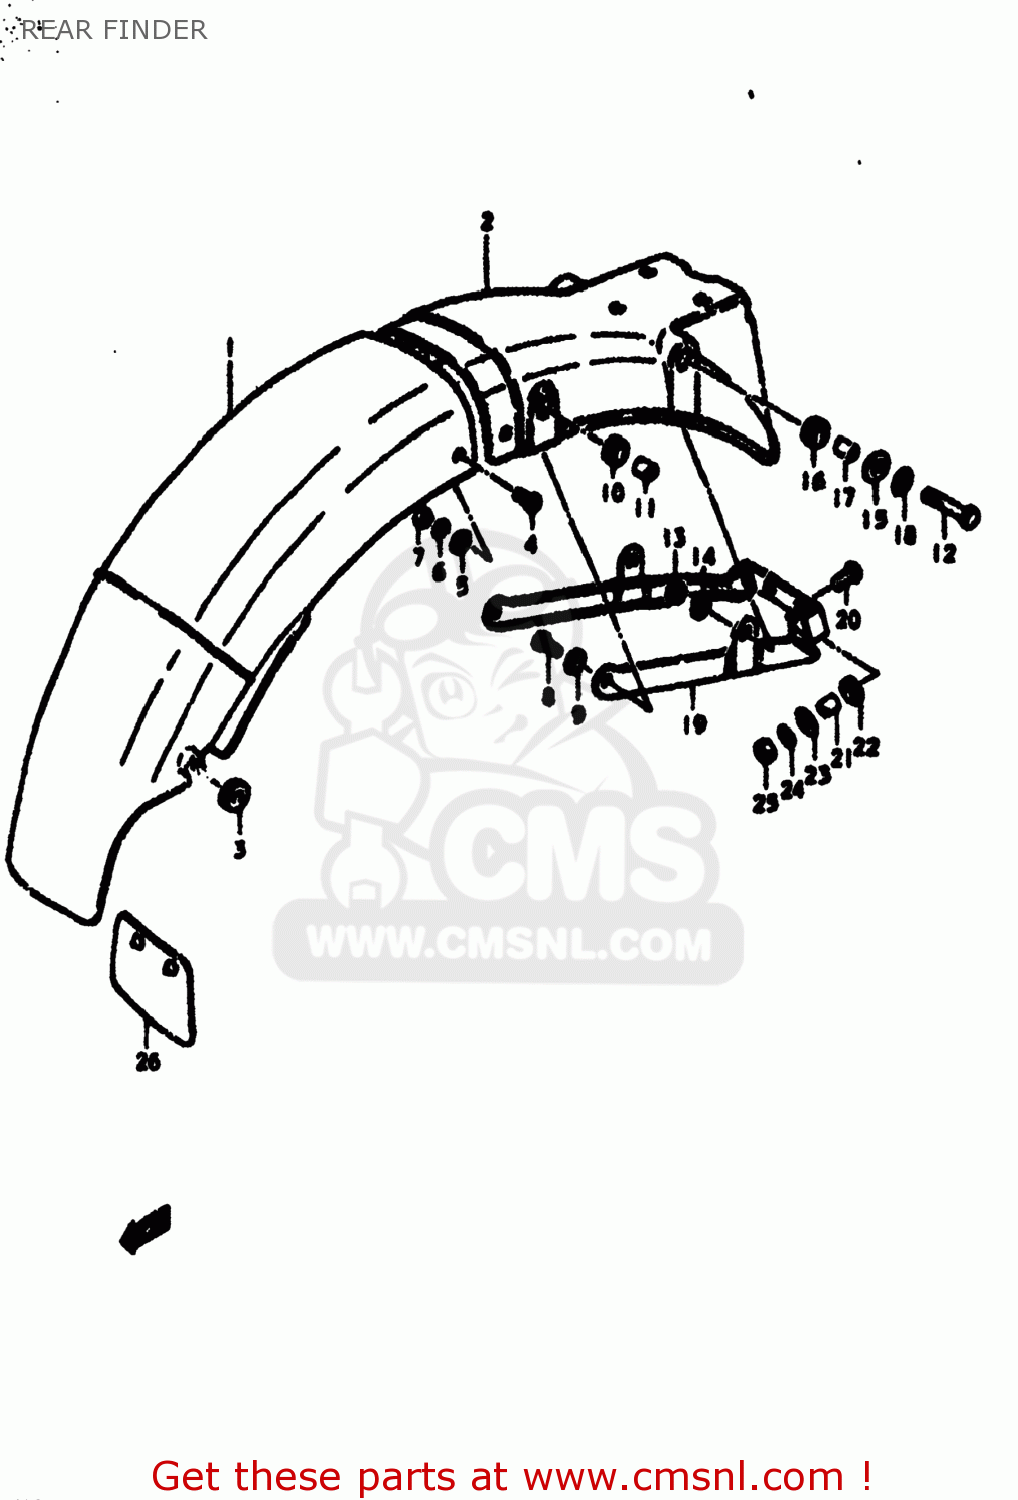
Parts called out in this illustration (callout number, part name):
1	FENDER,REAR
2	FENDER,REAR
3	CUSHION
4	SCREW
5	WASHER (5.5X16X1.2)
6	LOCK WASHER
7	NUT
8	BOLT
9	LOCK WASHER
10	CUSHION
11	SPACER(6.1X9X7.5)
12	BOLT
13	NUT
14	LOCK WASHER
15	WASHER(8.5X26X1.2)
16	CUSHION
17	SPACER (8.2X12X7.5)
18	WASHER
19	REINFORCEMENT,REAR FENDER
20	SCREW
21	SPACER (6.1X9X9)
22	CUSHION
23	WASHER(6,5X22X1.6)
24	LOCK WASHER
25	NUT
26	GUIDE,RR FENDER MUD
